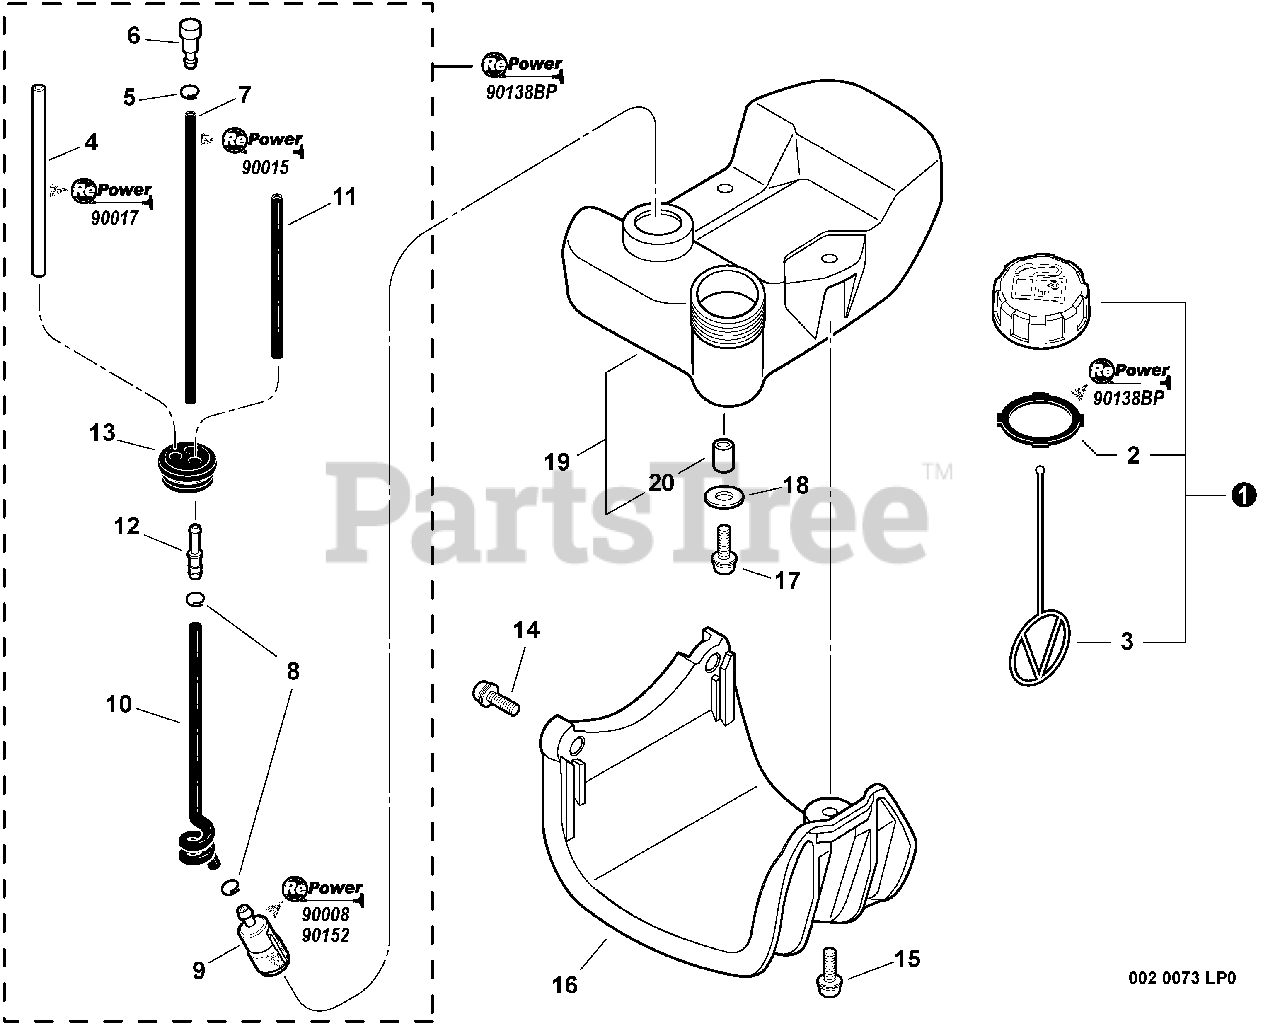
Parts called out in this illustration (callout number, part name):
1	CAP ASSY - ORANGE
2	GASKET, CAP
3	CONNECTOR, CAP
4	PIPE - 3X6X80 -- CLEAR
5	CLIP - 6.5
6	VENT, FUEL TANK
7	PIPE - 3X6X115 -- BLACK
8	CLIP - 6.5
9	FILTER, FUEL
10	PIPE, FUEL - SPIRAL
11	PIPE - 3X5X74 -- BLACK
12	CONNECTOR, PIPE
13	GROMMET
14	SCREW - 5X22
15	SCREW - 5X20
16	GUARD, FUEL TANK
17	SCREW - 5X16
18	WASHER - 5
19	FUEL TANK ASSY
21	RePower FUEL SYSTEM KIT
22	RePower TUNE-UP KIT
23	RePower FILTER KIT
24	RePower BULK PIPE - 25 FEET
25	RePower BULK PIPE - 25 FEET
